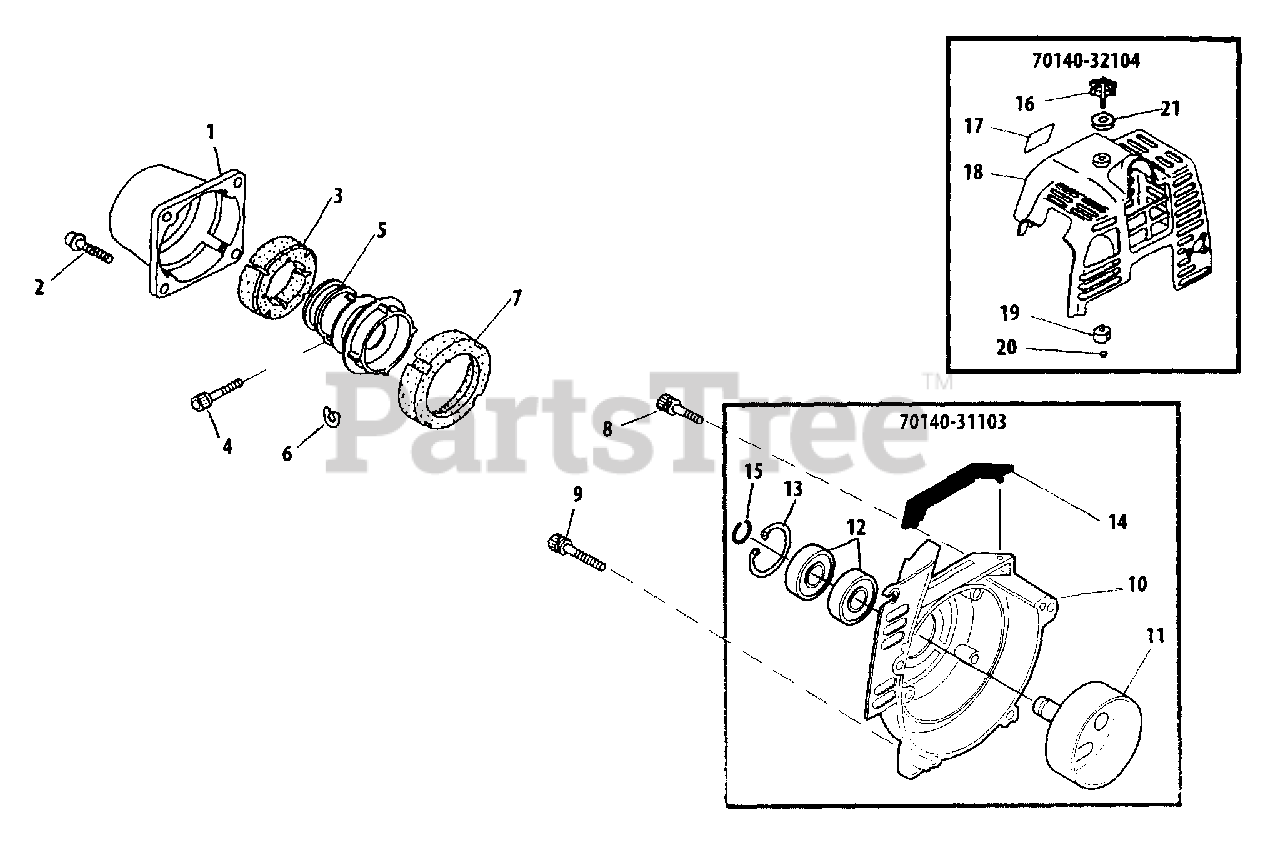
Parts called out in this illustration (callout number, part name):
1	COVER, AV CUSHION (RED)
2	BOLT M5×16
3	CUSHION, FRONT
4	BOLT M5×25
5	JOINT
6	D-WASHER
7	HOLDER, REAR CUSHION
8	BOLT M5×16
9	BOLT M5×35
10	COVER, FAN
11	DRUM, CLUTCH
12	BEARING, BALL 6000ZZ
13	RING, SNAP Ø26
14	CUSHION
15	RING, SNAP WR10
16	THUMBSCREW
17	LABEL
18	COVER, ENGINE
19	INSULATOR 5 MM
20	CLIP
21	WASHER, CONE M6
70140-31103	COVER ASSY, FAN
70140-32104	ENGINE COVER KIT - RED
